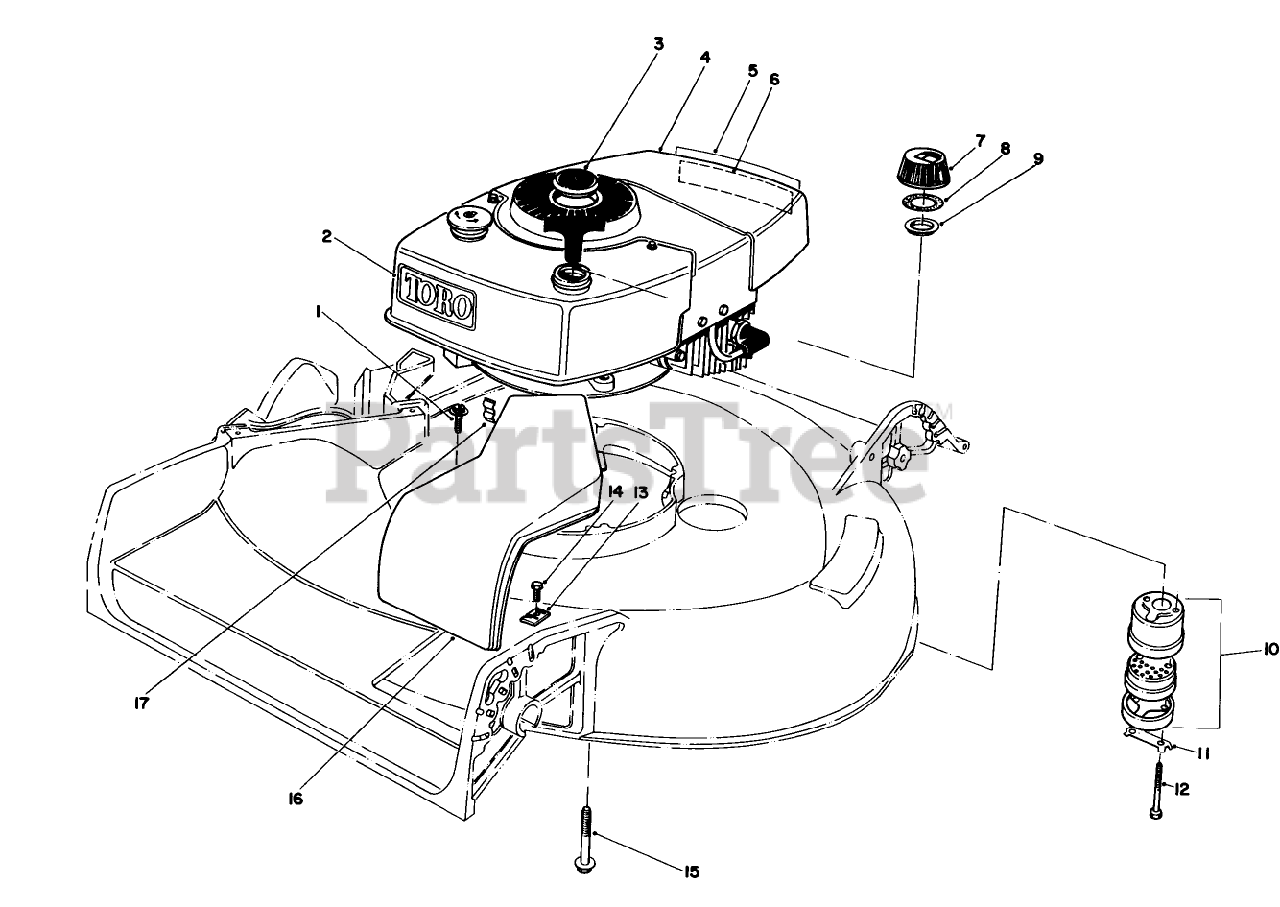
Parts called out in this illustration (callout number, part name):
1	SCREW
4	Engine
8	GASKET
10	MUFFLER ASM
11	CLIP - LOCKING
12	SCREW-HH
14	SCREW-THD ROLL, HWH
15	3/8-16 X 2-3/4 CAPSCR
